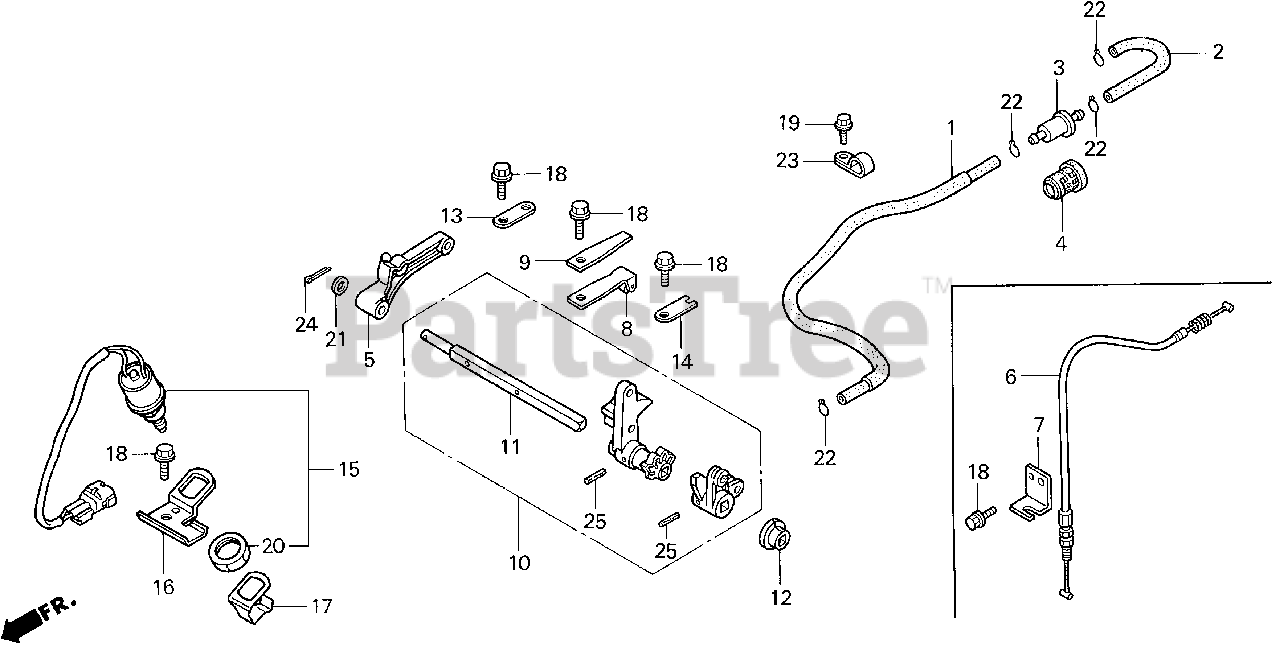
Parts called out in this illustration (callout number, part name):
1	TUBE, FUEL
2	TUBE B, FUEL
3	FILTER, FUEL
4	SUSPENSION, STRAINER
5	ARM, THROTTLE
8	SPRING, CLICK
9	SPRING, CLICK ASSIST
10	SHAFT, SHIFT
11	SHAFT, SHIFT
12	BUSH, SHAFT
13	PLATE, SHIFT
14	PLATE, SHIFT SHAFT
15	SWITCH ASSY., NEUTRAL
16	BRACKET, NEUTRAL SWITCH
17	PLATE, NEUTRAL SWITCH
18	BOLT, FLANGE (6X12)
19	BOLT, FLANGE (5X10)
20	NUT, HEX. (20MM)
21	WASHER (7.5MM)
22	CLIP, TUBE (B10)
23	CLIP (14MM)
24	PIN, SPLIT
25	PIN, SPRING (3X20)
